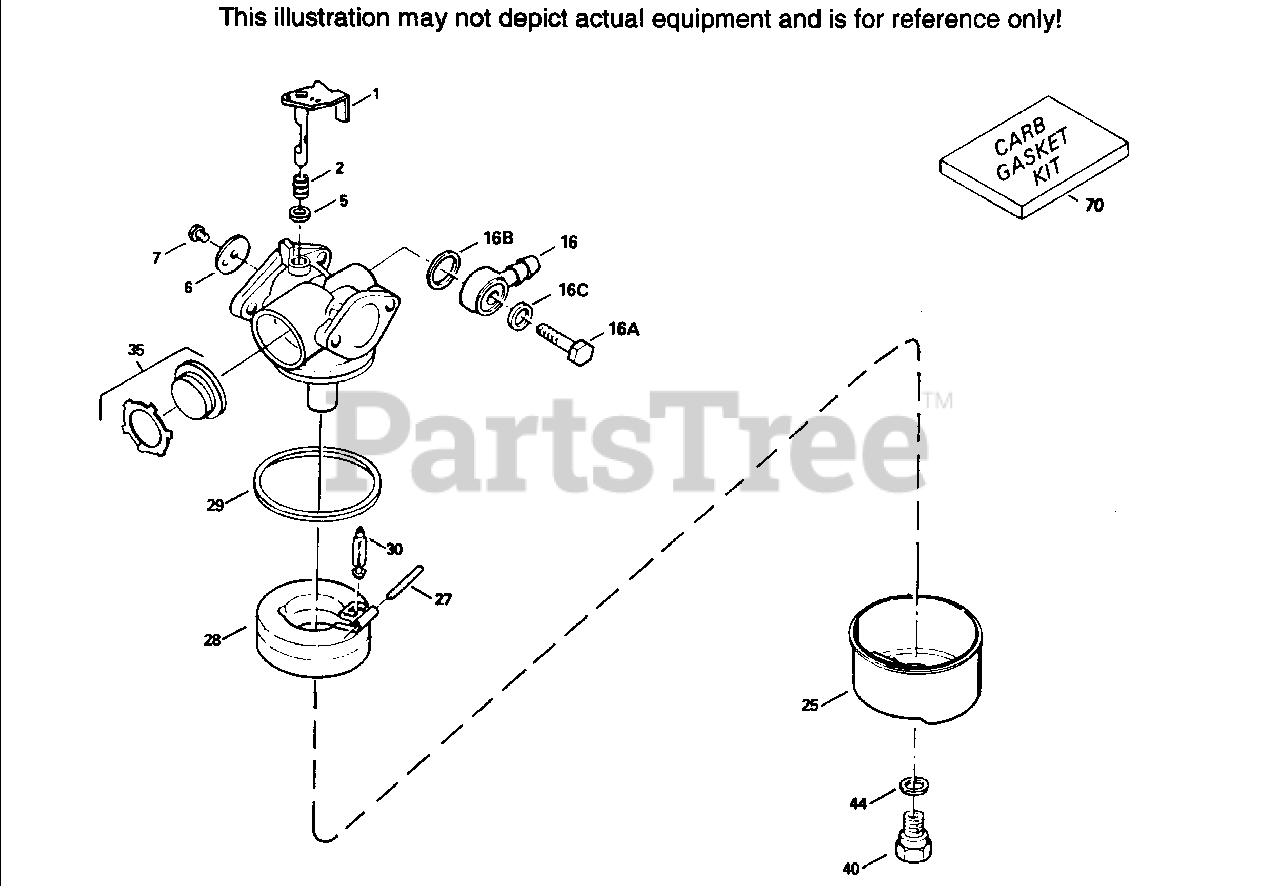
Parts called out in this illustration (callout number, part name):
1	Throttle Shaft & Lever Ass'y.
2	Throttle Return Spring
5	* Dust Seal
6	Throttle Shutter
7	Throttle Shutter Screw
16	Fuel Fitting (Incl. 16A & 16C)
16A	Fitting Screw
16B	* Fuel Fitting Gasket
16C	* Fitting Screw Gasket
25	Float Bowl
27	Float Shaft
29	* O Ring, Float Bowl-to-body
30	Inlet Needle
35	Primer Bulb/Retainer Ring
40	High Speed Bowl Nut
44	* Bowl Nut Washer
70	Gasket Kit Incl. items marked PK inn otes
